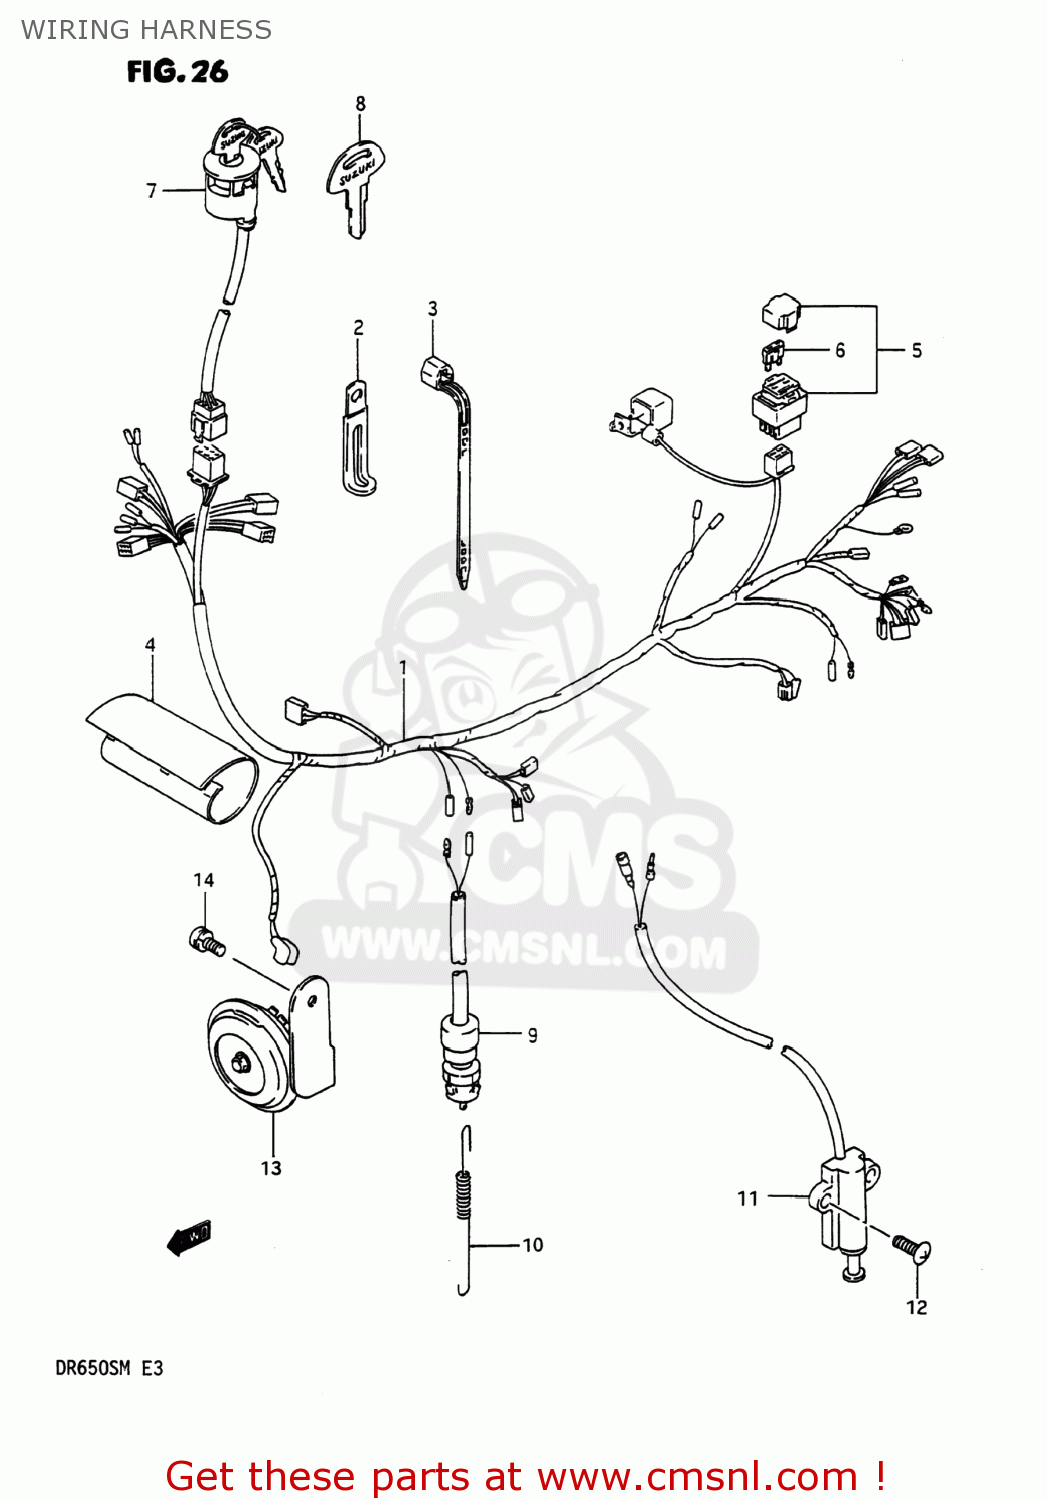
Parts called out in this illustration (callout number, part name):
1	HARNESS,WIRING
2	CLAMP
3	CLAMP(L:125)
4	BOOT,WIRING HARNESS
5	BOX ASSY,FUSE
6	FUSE(15A)
7	SWITCH ASSEMBLY,IGNITION
8	KEY,BLANK
9	SWITCH ASSEMBLY,STOP LAMP
10	SPRING
11	SWITCH ASSY,SIDE STAND WARNING
12	SCREW
13	HORN ASSY
14	SCREW
